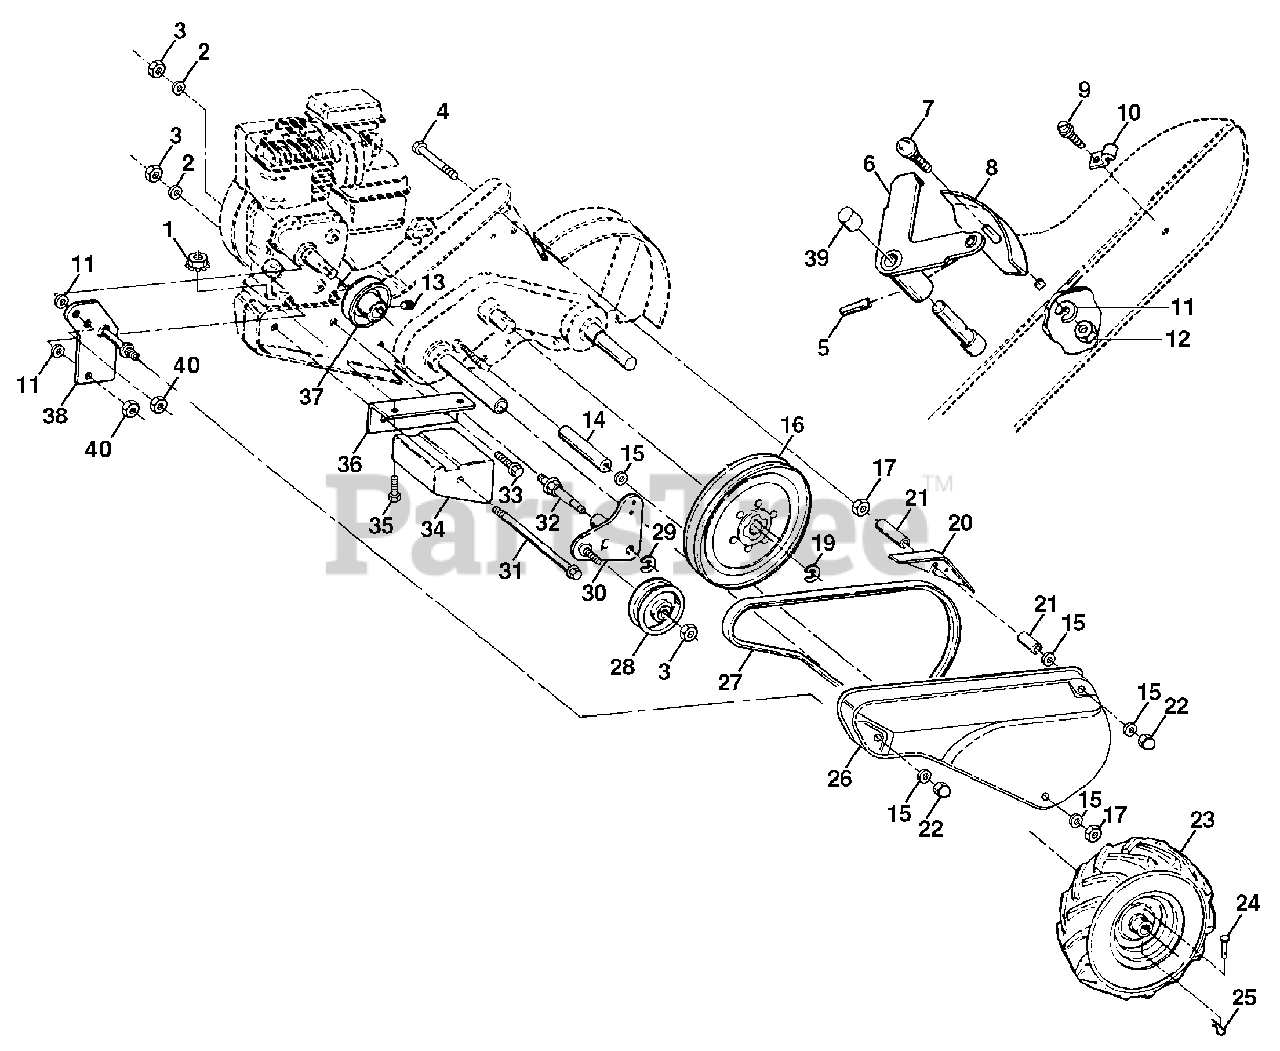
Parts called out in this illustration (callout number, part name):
1	Nut, Keps 5/16-18
2	Washer, Lock 3/8
3	Nut, Hex 3/8-16
4	Bolt, Hex 5/16-18 x 4-1/4
5	Pin, Roll
6	Lever, Shift
7	Bolt, Carriage 1/4-20 x 1/2 Gr. 5
8	Plate, Shift Indicator
9	Screw, Hex, Washer Head, Slotted #10-24 x 1/2
11	Washer, Lock 1/4
12	Nut, Hex 1/4-20
13	Screw, Set, Hex 5/16-18 x 3/8
14	Spacer, Split 0.327 x 0.42 x 2.68
15	Washer 11/32 x 11/16 x 16 Ga.
16	Sheave, Transmission
17	Nut, Hex 5/16-18
18	Spacer, Split 0.327 x 0.42 x 1.75
19	Key, Square 3/16 x 1-1/8
20	Guard, Pinch Point
21	Spacer, Split 0.327 x 0.42 x 1.627
22	Nut, Cap 5/16-18
23	Tire Valve
24	Rivet, Drilled
25	Clip, Hairpin
26	Guard, Belt
28	Pulley, Idler
29	Ring, Klip
30	Bracket, Idler
31	Bolt, Hex 5/16-16 x 12
32	Shaft, Idler Arm
33	Bolt, Hex 3/8-16 x 1
34	Counterweight, L. H.
35	Bolt, Hex 5/16-18 x 1-1/2
36	Bracket, Reinforcement, L. H.
37	Sheave, Engine
38	Bracket, Guard Belt
39	Cap, Plunger
40	Nut, Lock w/insert 1/4-20
